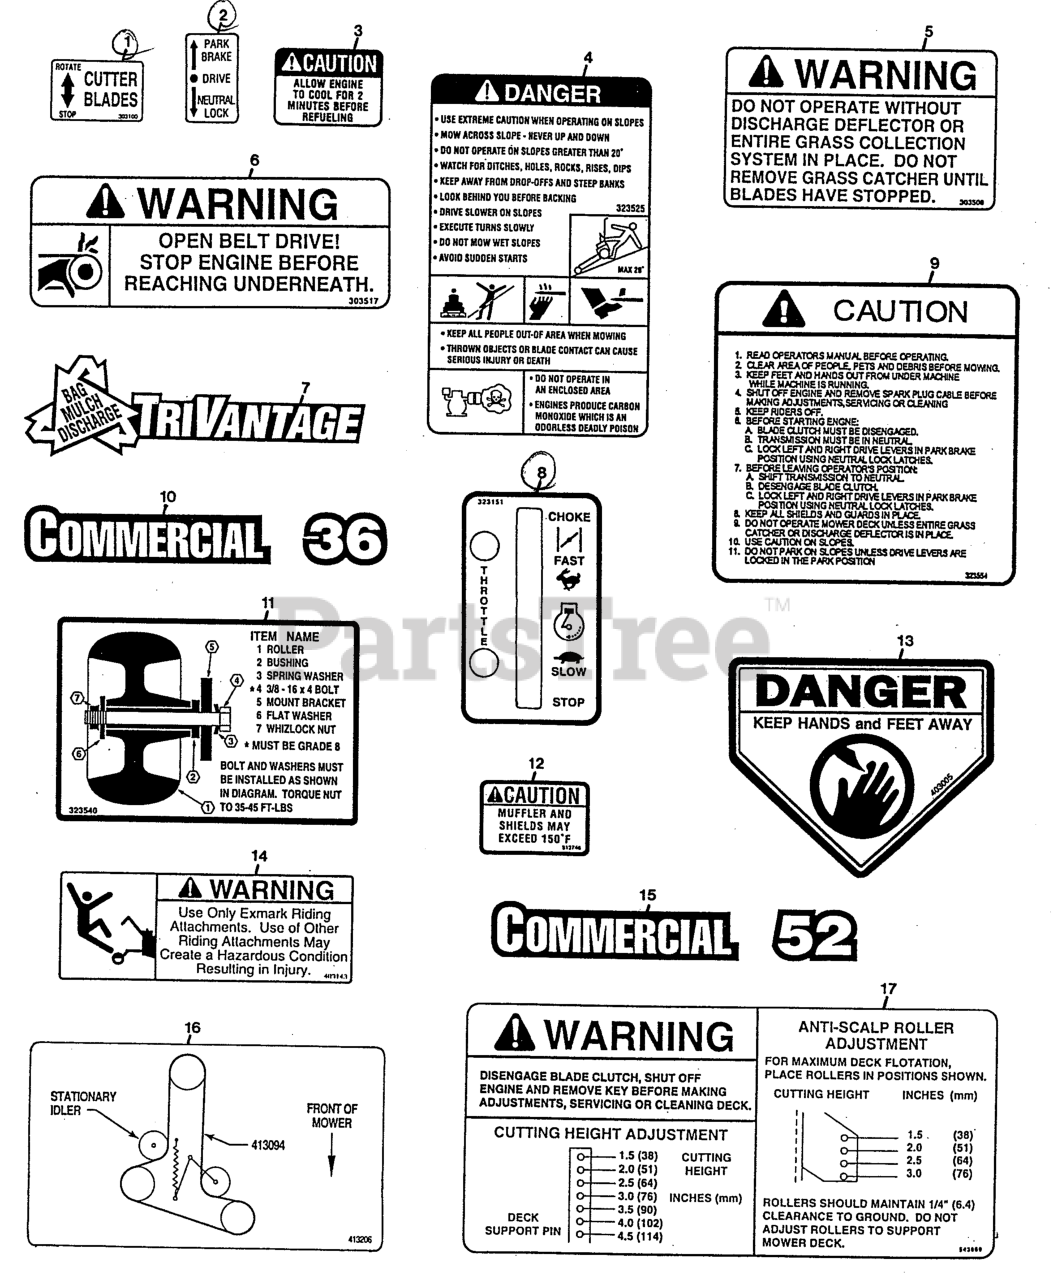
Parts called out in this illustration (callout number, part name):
1	Decal, Cutter Blade
2	Decal, Neutral/P.Brake
3	Decal, 2 Min Cool
4	Decal, Danger
5	Decal, Discharge Warning
6	Decal, Belt Drive
7	Decal, Trivantage
8	Decal, Throttle
9	Decal, Instructional
10	SCREW-HHF
11	Decal, Roller Mounting
12	Decal, Muffler
13	Decal, Danger (36)
14	Decal, Sulky Warning
15	Decal, Commercial 52
16	Decal, Belt Routing (36")
17	Decal, Mower Deck
